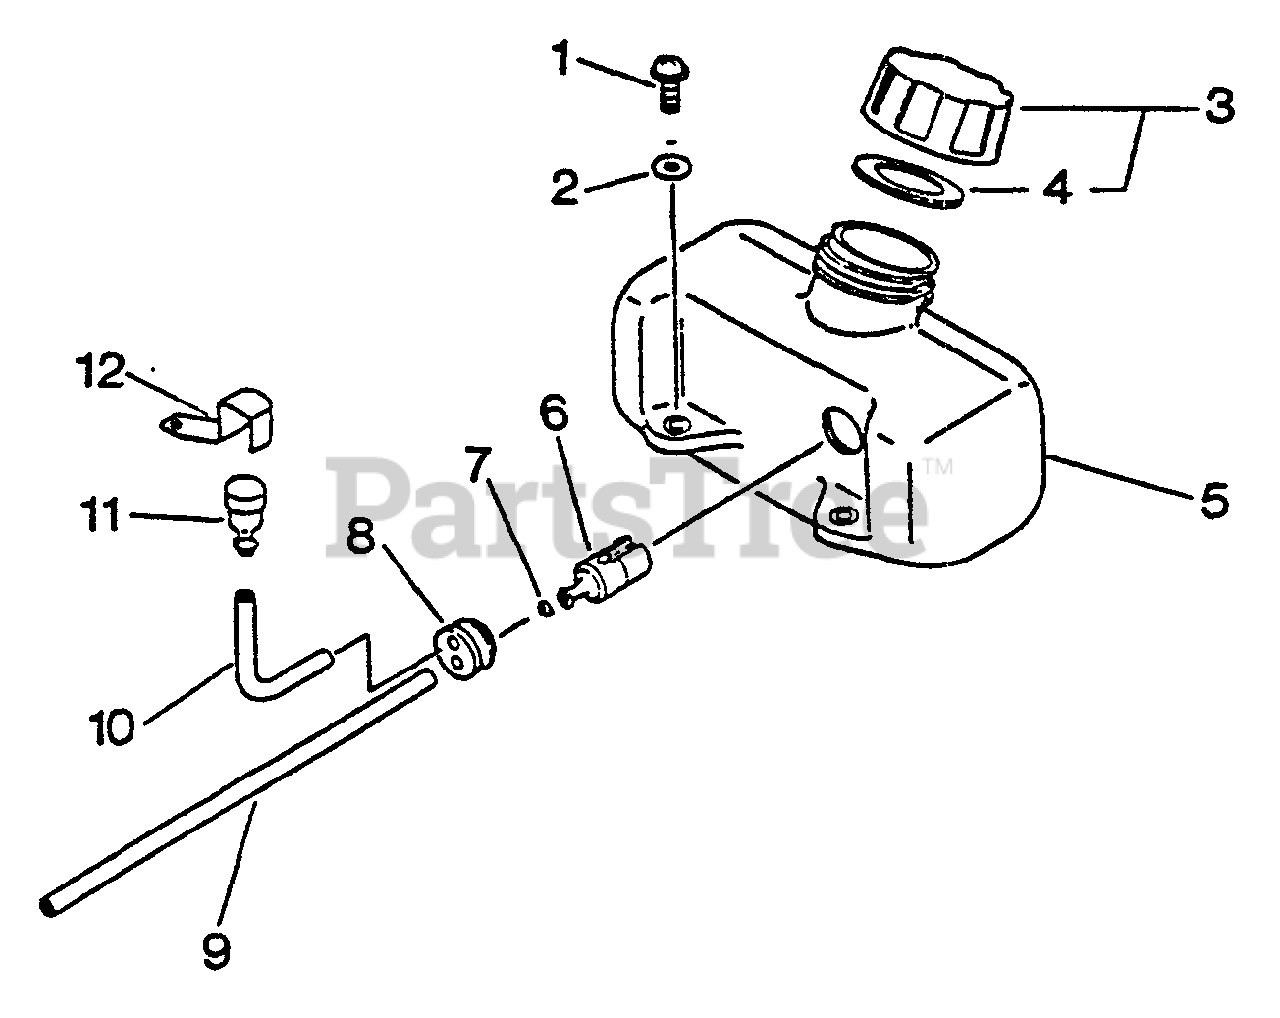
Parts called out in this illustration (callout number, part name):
1	SCREW - 5X16
2	WASHER - 5
3	CAP ASSY
4	GASKET, CAP
5	TANK, FUEL
6	FILTER, FUEL
7	CLIP - 6
8	GROMMET
9	PIPE - 3X5X180 -- BLACK
10	PIPE - 3X6X70 -- CLEAR
11	VENT, FUEL TANK
